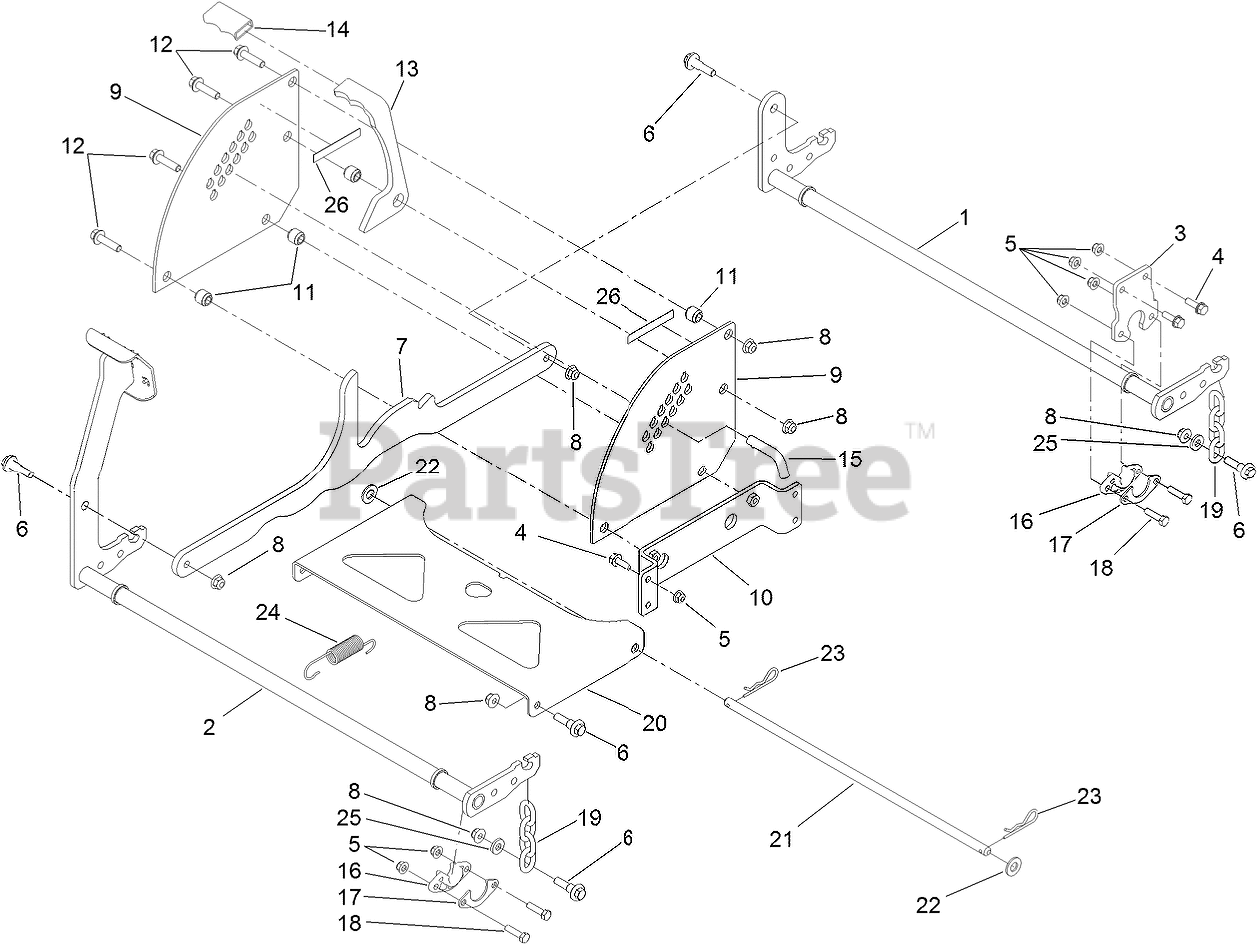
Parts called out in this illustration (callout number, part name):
1	PIVOT-REAR
2	PIVOT-FRONT
4	SCREW-HHF
5	NUT-HF, NI
6	BOLT-SHOULDER
7	LINK-HOC
8	NUT-HF, NI
9	PLATE-DECK, LIFT
10	PLATE-LIFT
11	SPACER-STEP, DOUBLE
12	SCREW-HHF
13	LOCK-TRANSPORT, HOC
14	GRIP-FLAT
15	PIN-HOC
16	BUSHING-FLANGE
17	GUSSET-LIFT, DECK
18	SCREW-HH
19	CHAIN-DECKLIFT
20	PAN-PIVOT, DECK
21	ROD-PIVOT, DECK
22	WASHER-FLAT
23	PIN-COTTER
24	SPRING-EXTENSION
25	SPACER
26	PAD-RUBBER
